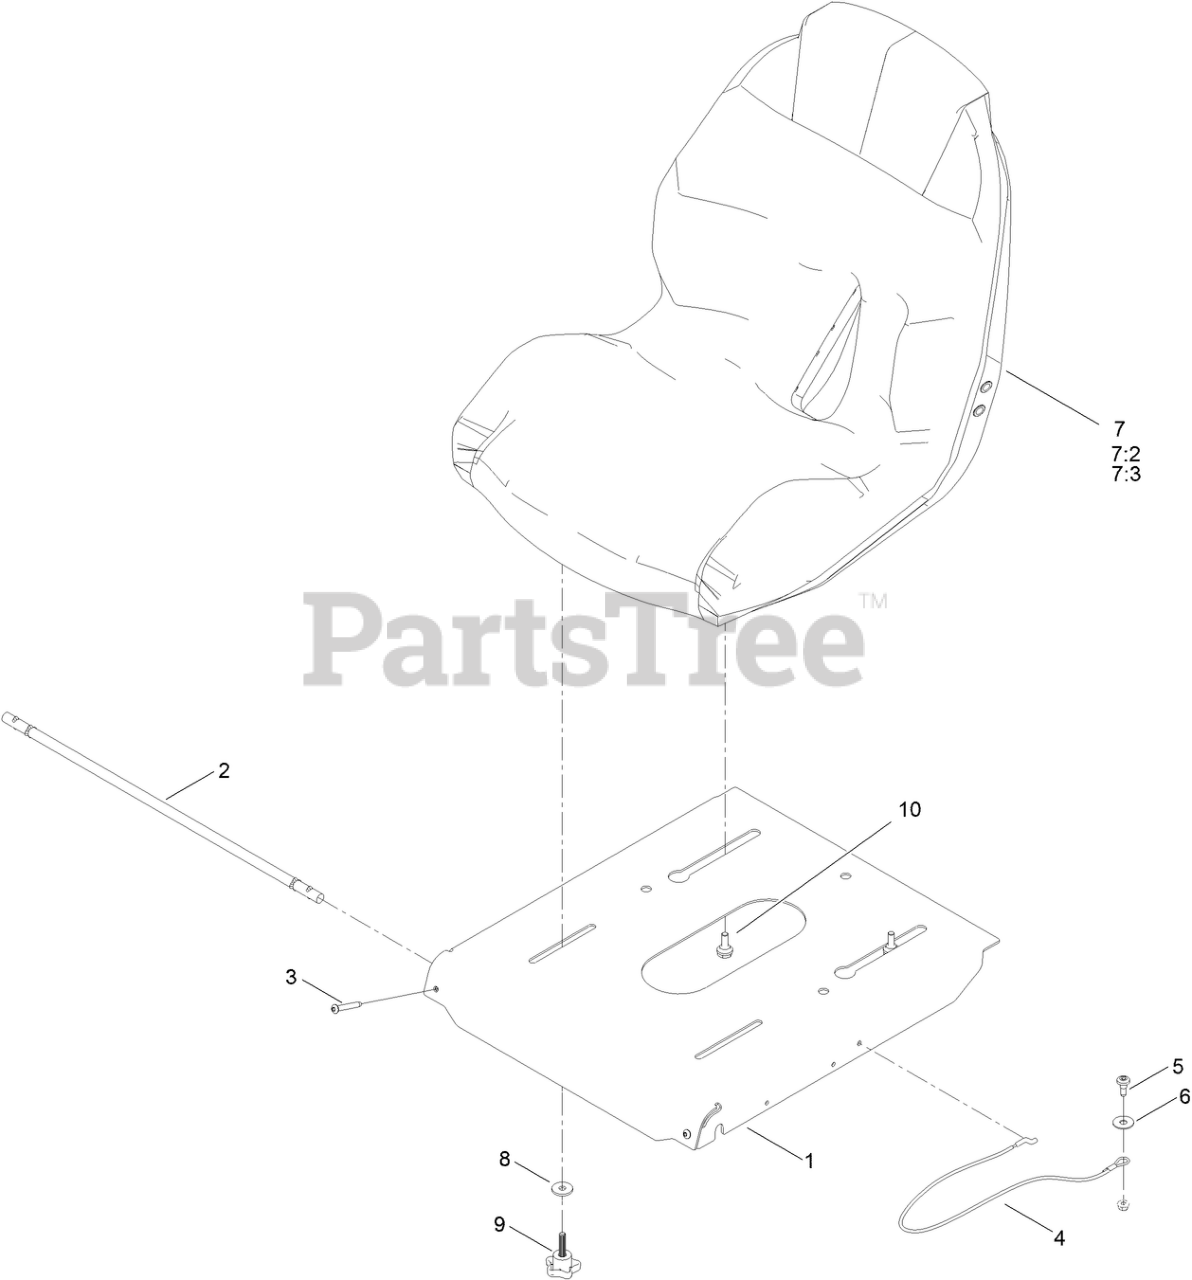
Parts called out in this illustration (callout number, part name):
1	PAN-SEAT
2	ROD-PIVOT
3	SCREW-TBH,THD ROLL
4	CABLE-LANYARD, 26.75"
5	SCREW-SHOULDER
6	WASHER-FLAT
7	SEAT ASM - SEAT KING SK130
7:2	COVER-SEAT
7:3	SWITCH-BAIL
8	WASHER-FRICTION
10	BOLT-SHOULDER,HFH
